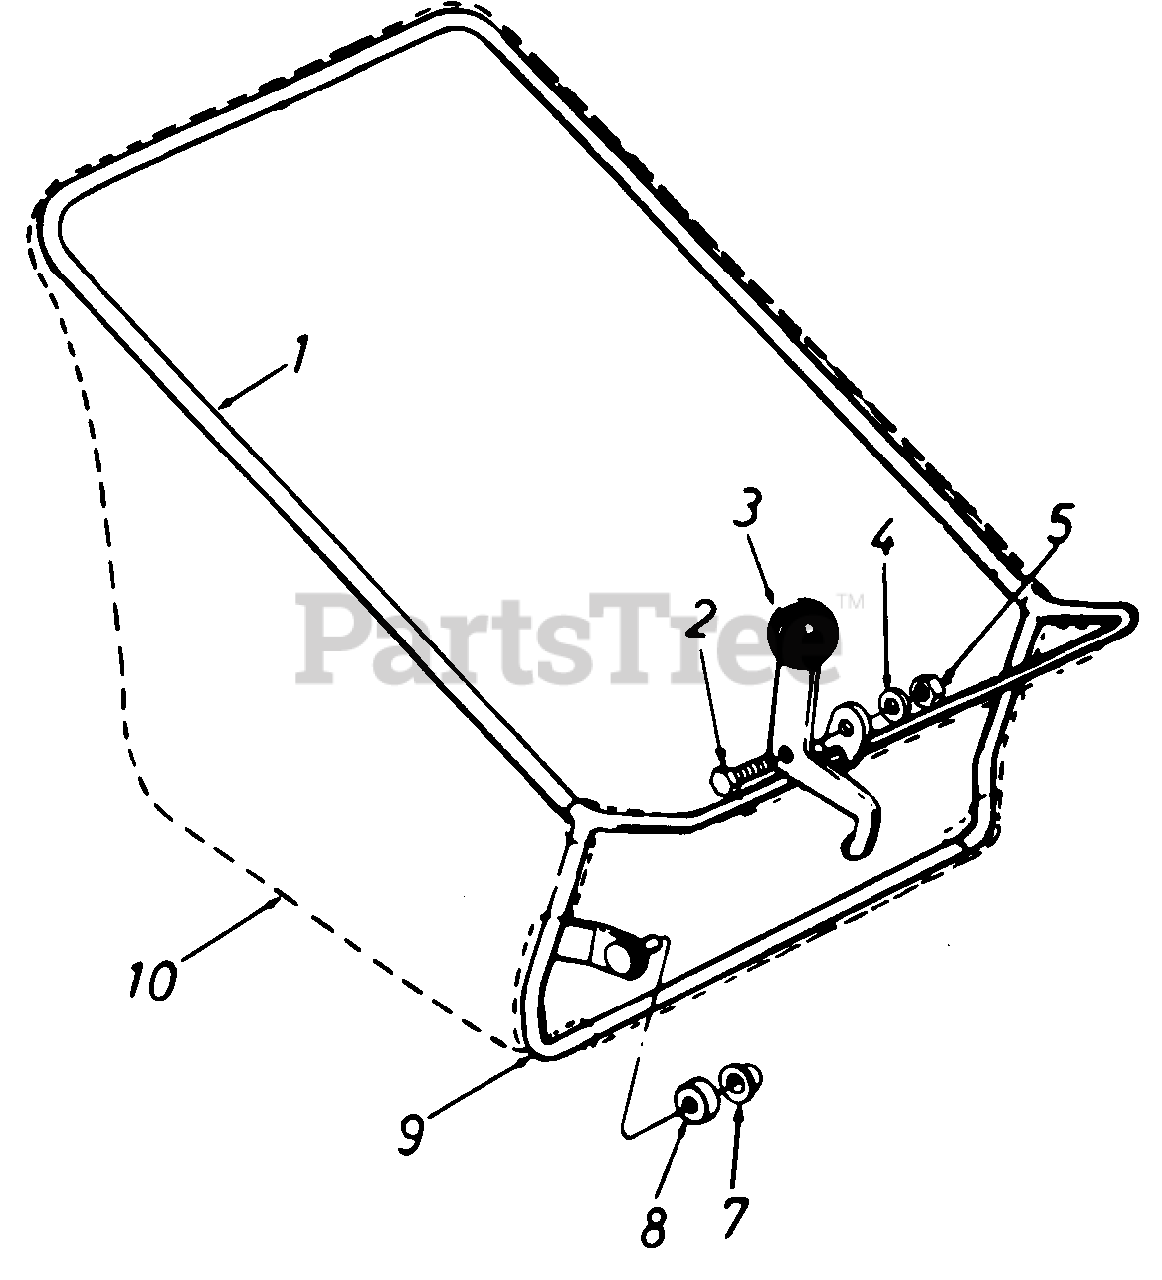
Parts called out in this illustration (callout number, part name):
1	Upper Frame
2	Shld. Scr. .437 Dia. x .180
3	Cam Lever Grip Ass'y.
4	L-Wash. 5/16" I.D.
5	Hex Nut 5/16-18 Thd.
7	Push Cap
8	Plastic Roller
9	Lower Frame Ass'y.
10	Grass Bag
